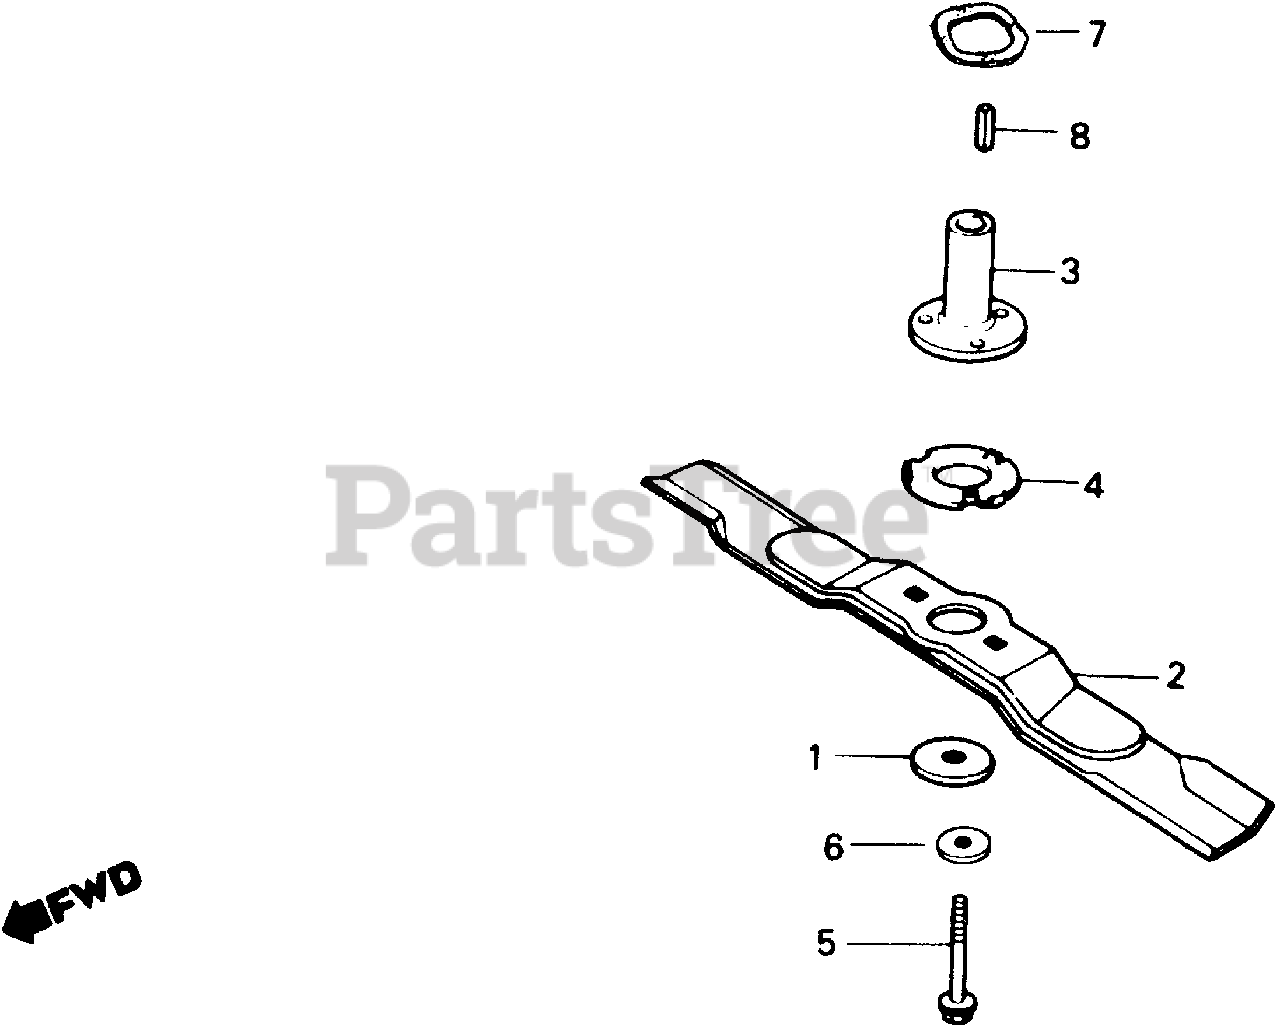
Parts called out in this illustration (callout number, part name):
1	WASHER (42X8.5)
2	BLADE, ROTARY
3	HOLDER, BLADE (NOT AVAILABLE)
4	WASHER, BLADE HOLDER
5	BOLT, SPECIAL
6	WASHER, SPECIAL (22X8.5X2)
7	WASHER, WAVE
8	KEY, INCH (1/8)
